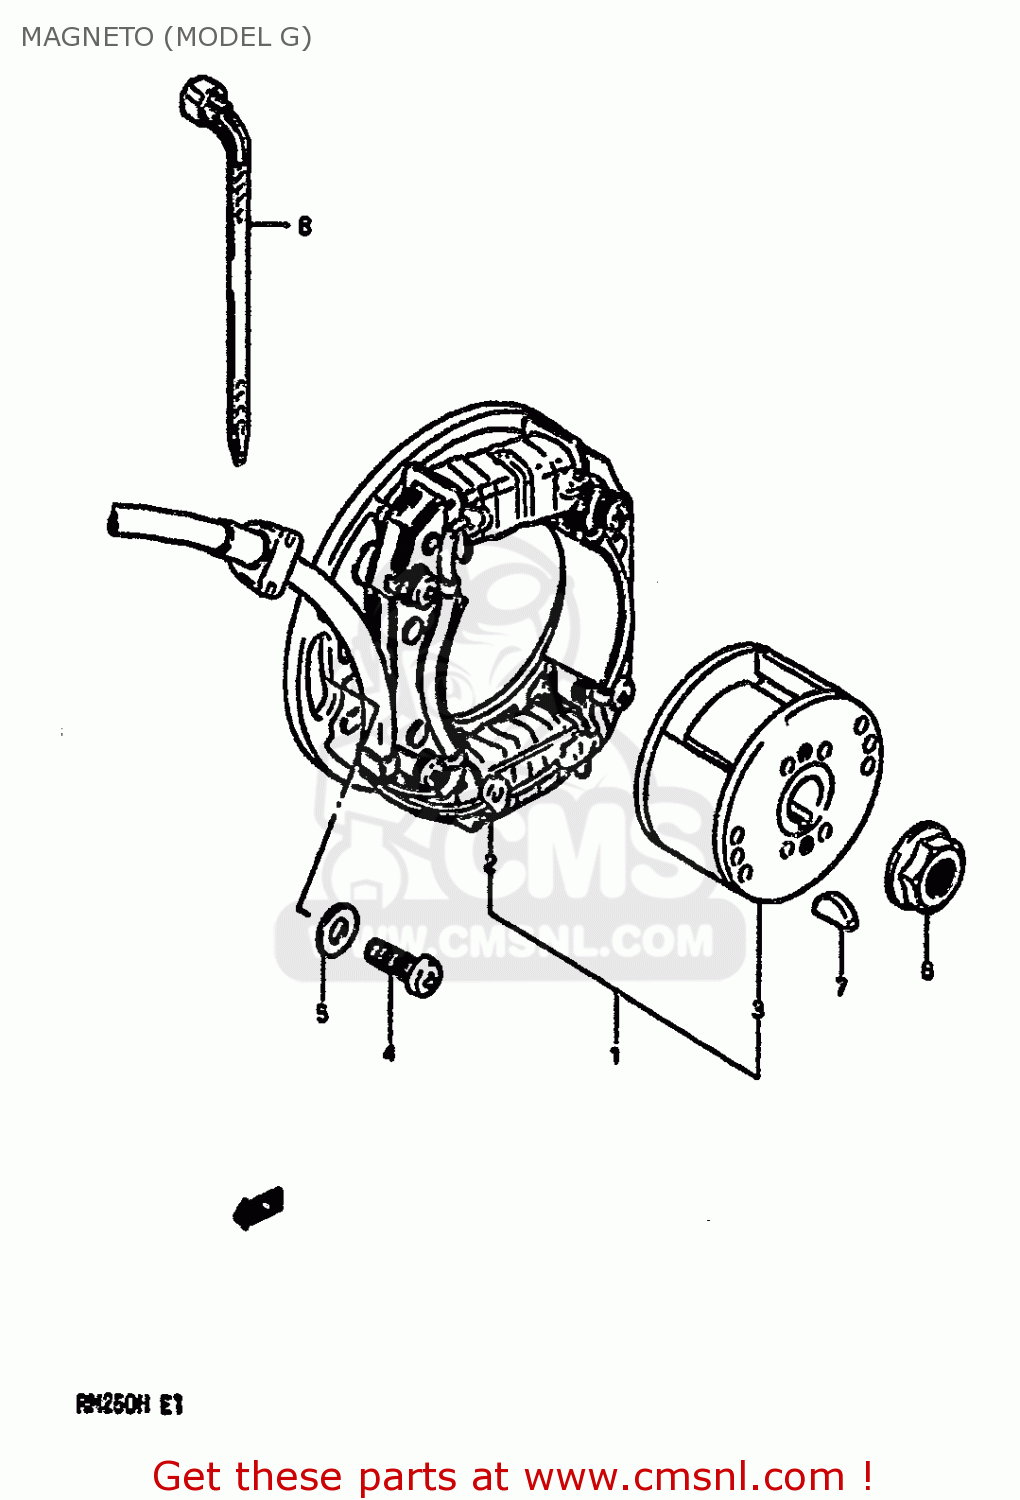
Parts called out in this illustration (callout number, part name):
1	MAGNETO ASSEMBLY
2	STARTER ASSY
3	ROTOR,FLYWHEEL
4	SCREW
5	WASHER
6	NUT
7	KEY 4MM
8	CLAMP(L:125)
